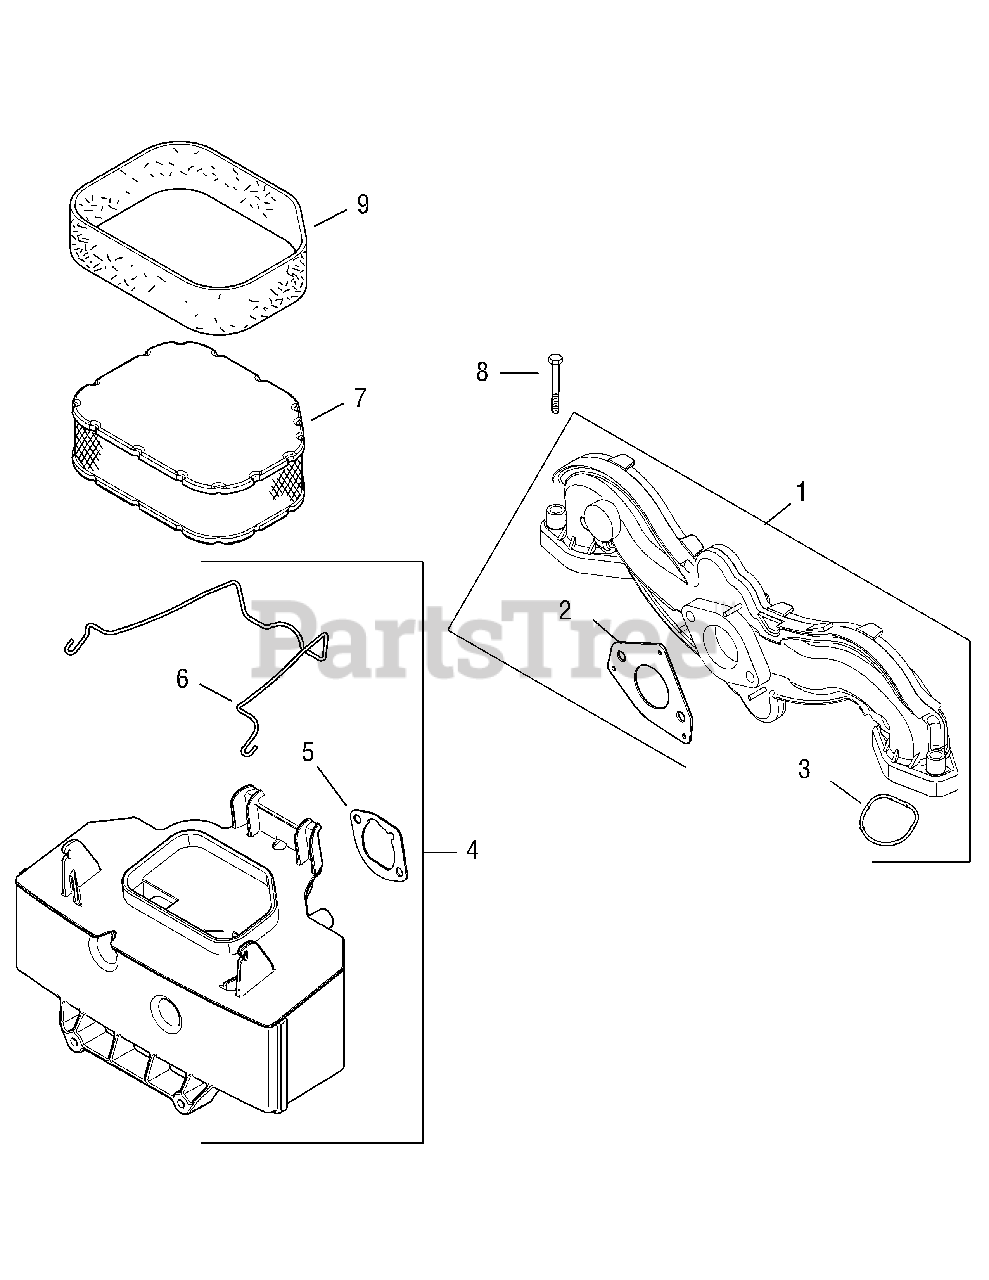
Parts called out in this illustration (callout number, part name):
1	Manifold, intake (Includes 2,3)
2	Gasket, carburetor
3	O-Ring, intake port
4	Base, air cleaner (Includes 5,6)
5	Gasket, air cleaner base
6	Latch, air cleaner element
7	Element, air cleaner
8	Screw, hex. flange M6x1.0x40
9	Pre-cleaner, element
